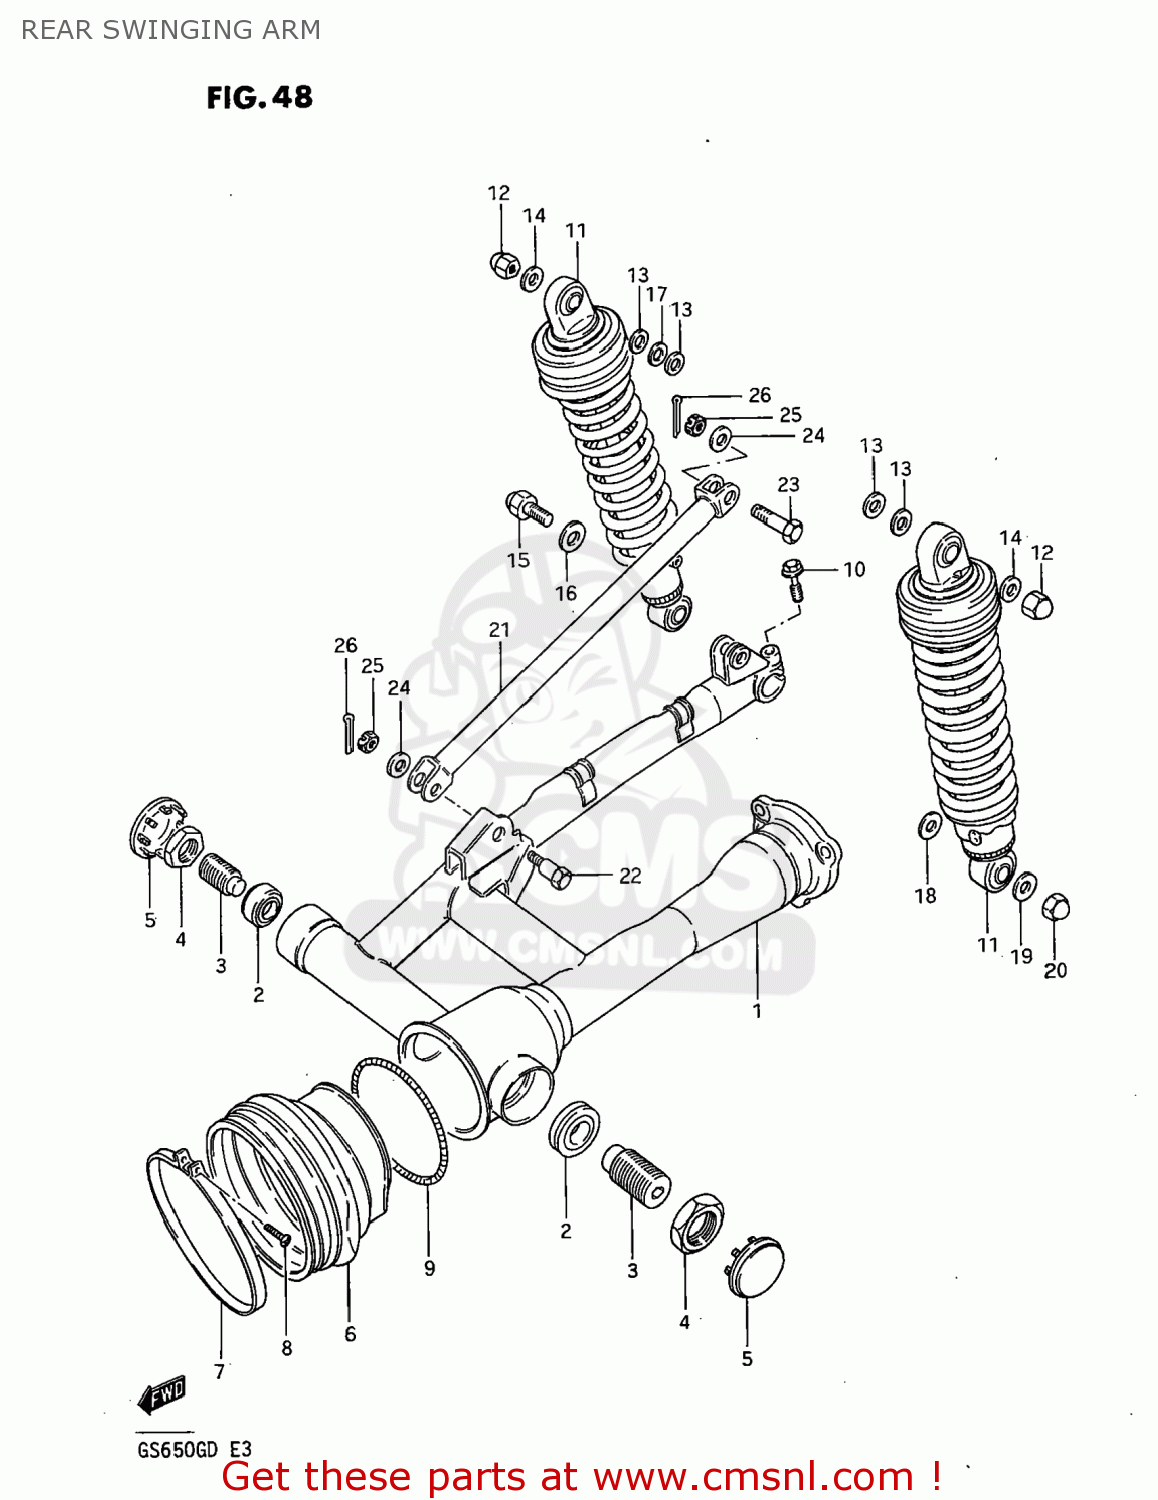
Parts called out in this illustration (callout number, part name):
1	SWING ARM ASSEMBLY,REAR
2	BEARING(15X35X11.75)
3	BOLT,REAR SWING ARM PIVOT
4	NUT (22MM)
5	CAP,REAR SWING ARM PIVOT
6	BOOT,PROPELLER SHAFT
7	CLAMP
8	SCREW 4X25
9	SPRING,PROPELLER SHAFT
10	BOLT
11	ABSORBER ASSEMBLY,REAR SHOCK
12	NUT
13	WASHER
14	WASHER
15	BOLT 12X33
16	WASHER (12.5X24X1.6)
17	WASHER (12.5X24X3.2)
18	WASHER
19	WASHER
20	NUT, LOWER LH
21	TORQUE LINK,REAR
22	BOLT
23	BOLT(10X39)
24	WASHER
25	NUT
26	PIN 20X20
